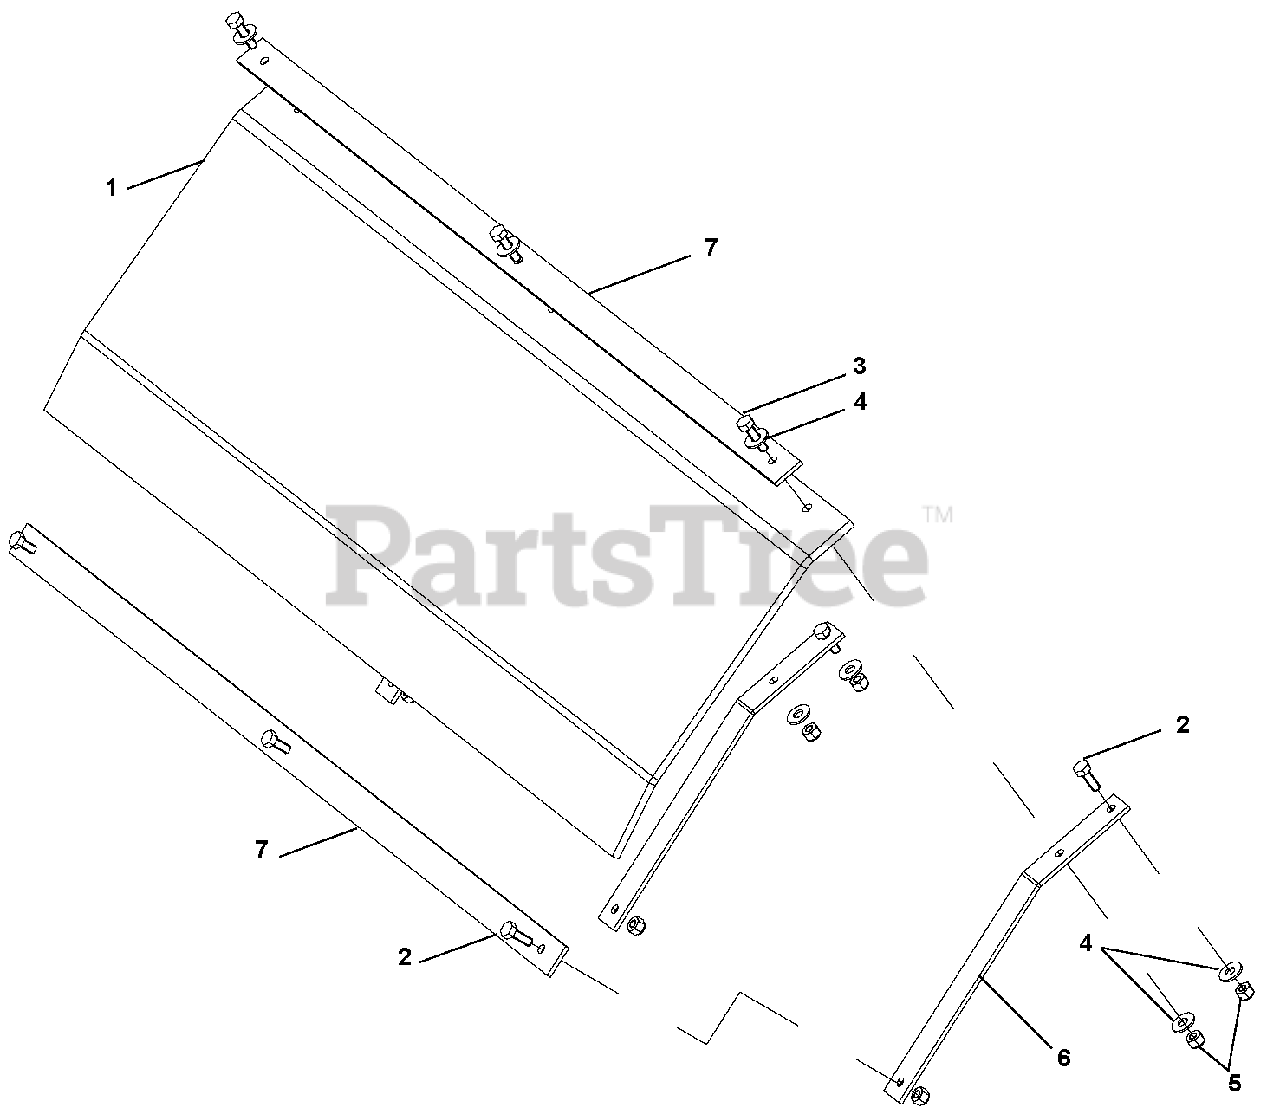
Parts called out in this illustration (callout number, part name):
1	DEFLECTOR, 3' MCD
2	@BLT-HEX .25-20X1.25 GR5 YWZC
3	@BLT-HEX .25-20X1.50 GR5 YWZC
4	@WSHR-FL-STL.312X.734X.065 YWZ
5	@NUT-LK-NYL .250-20 YWZC
6	STRAP, DEFLECTOR SUPPORT
7	STRAP, SUPPORT
